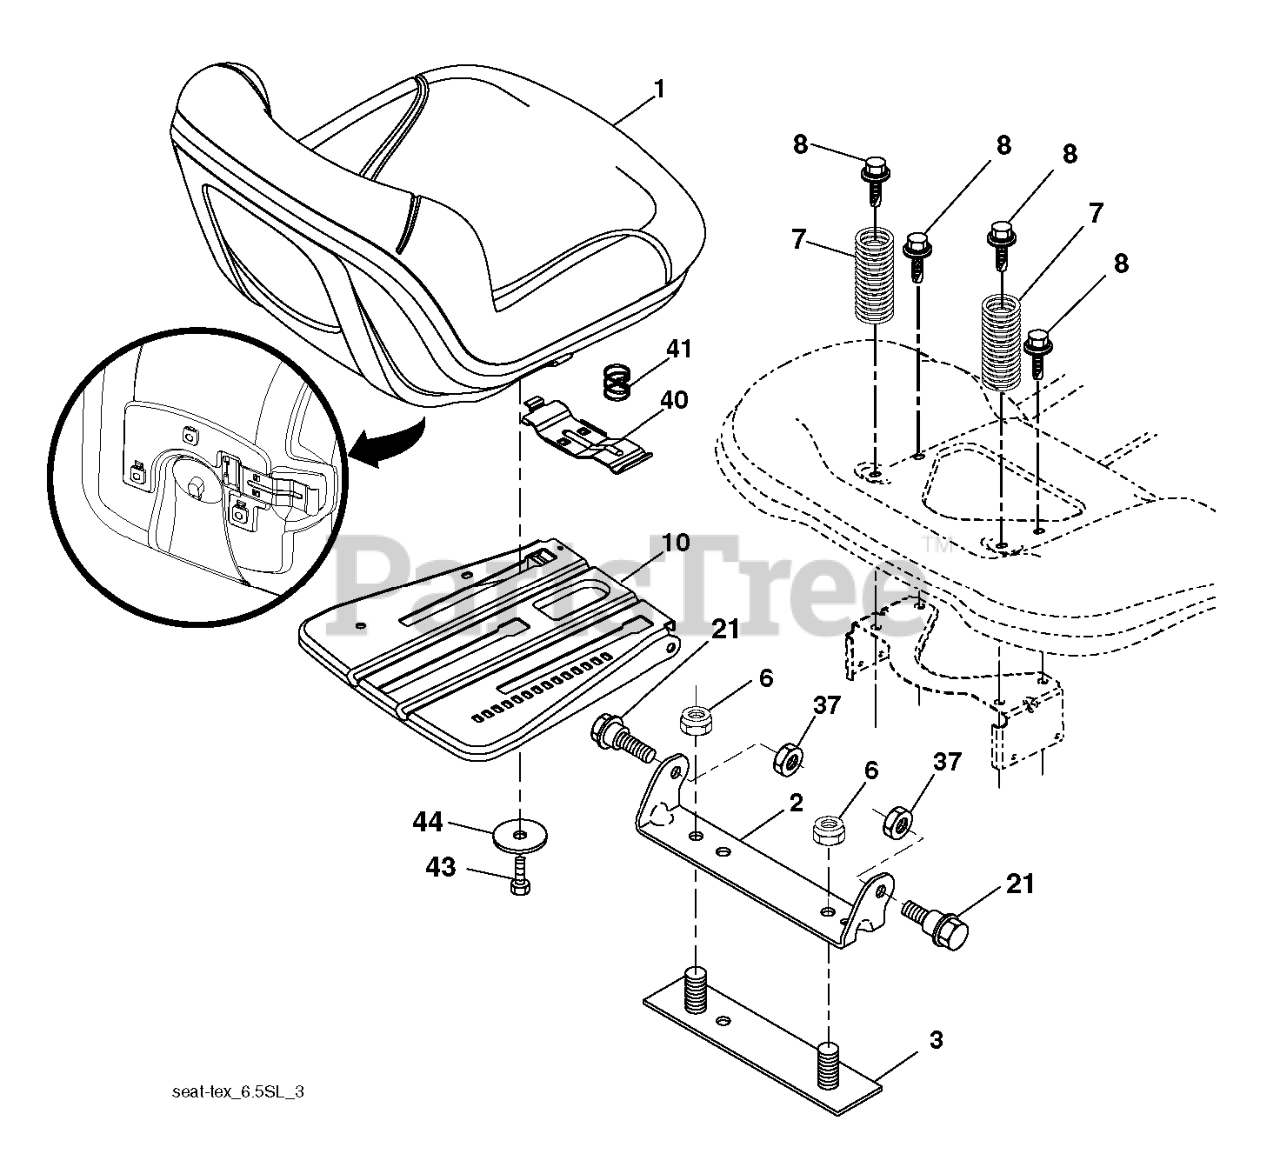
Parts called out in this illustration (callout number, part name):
1	SEAT.TH150.MS498.GRY.HUSQ.TEX
2	BRKT.PIVOT.FENDER
3	STRAP
6	NUT
7	SPRING COMPRESSION
8	BOLT.5/16-18UNCX3/4 W/SEMS.BLK
10	PAN.ASM.SEAT.3PT
21	BOLT.SHOULDER.5/16-18
37	NUT.71038.31-18.HEX.NYLOCK
40	HANDLE.SLIDE.SEAT.TEX.GREY
41	SPRING.LATCH.SEAT.TEX
44	WASHER 13/32 X 2-3/8 X 12GA
